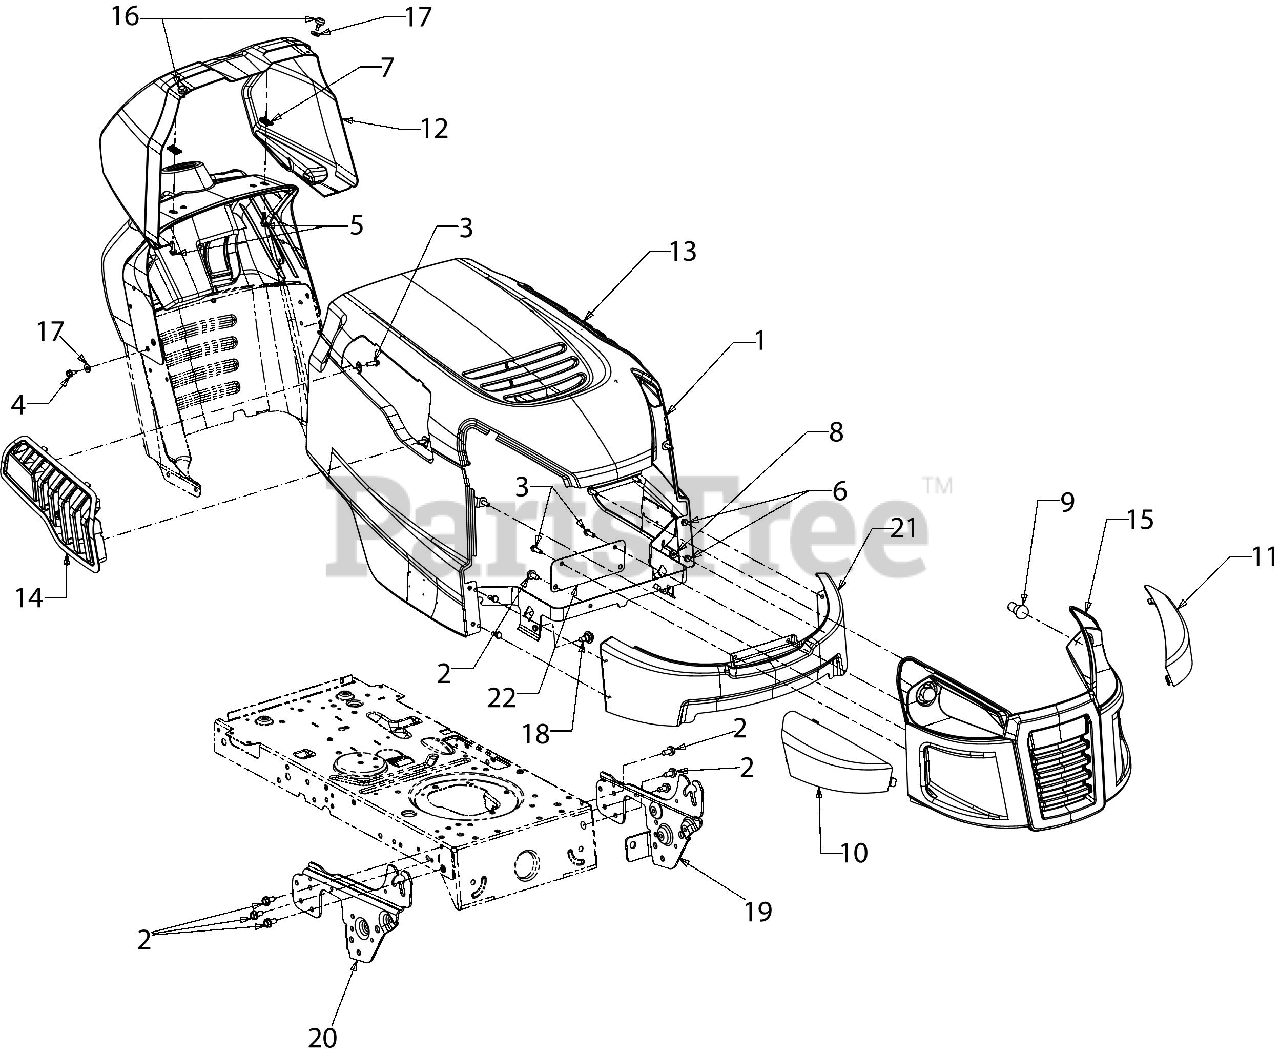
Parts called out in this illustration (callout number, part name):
2	SCREW 5/16-18 x .750
3	SCREW 1/4 x .750
4	SCREW 1/4-20 X.500
5	SCREW 1/4-20 x .750
6	SCREW 1/4-20 x .620 GR5
7	SPEED NUT
8	FLANGE LOCK NUT
9	MINIATUURE BULB 12V
10	LENS (RH)
11	LENS (LH)
12	DASH COLLER
13	HOOD SCOOP (LH)
14	HOOD SCOOP (RH)
15	GRILLE(S STYLE) W/O LABEL
16	BUMPER, .62 DIA x .3
17	FLAT WASHER
18	SHOULDER SCREW .43X.29X5/16-18 TT
22	LOWER GRILLE BRACKET
